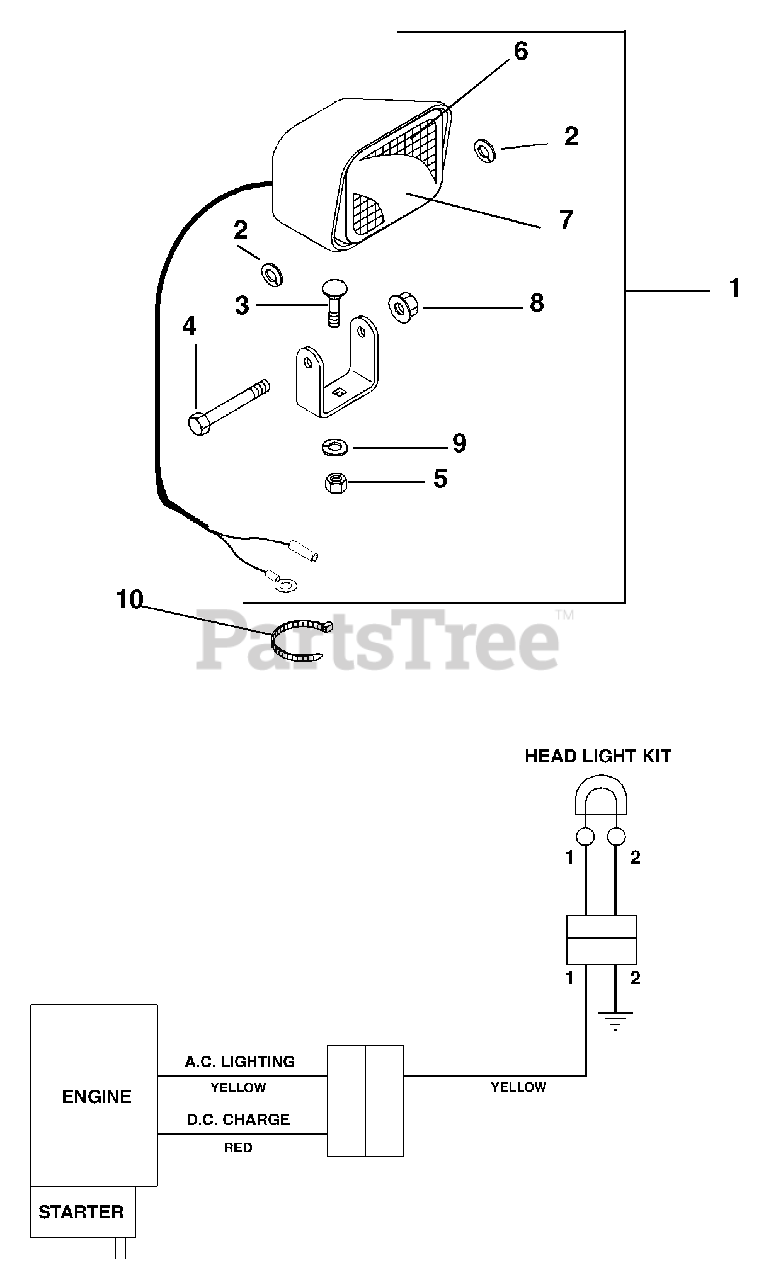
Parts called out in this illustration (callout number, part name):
1	HEADLIGHT
2	@WSHR-LK-EXT.326X.599X.031YWZC
3	@BLT-RDHDSQNK .31-18X1.00 G5YZ
4	@BLT-HEX .31-18X2.50 GR5 YWZC
5	@NUT-HEX .31-18 YWZC
6	LENSE-FLOOD
8	@NUT-SPNLK-FLG .312-18 YWZC
9	WSHR-LK .312X.097 HVY YWZC
10	CABLE TIE LG 5-1/2
